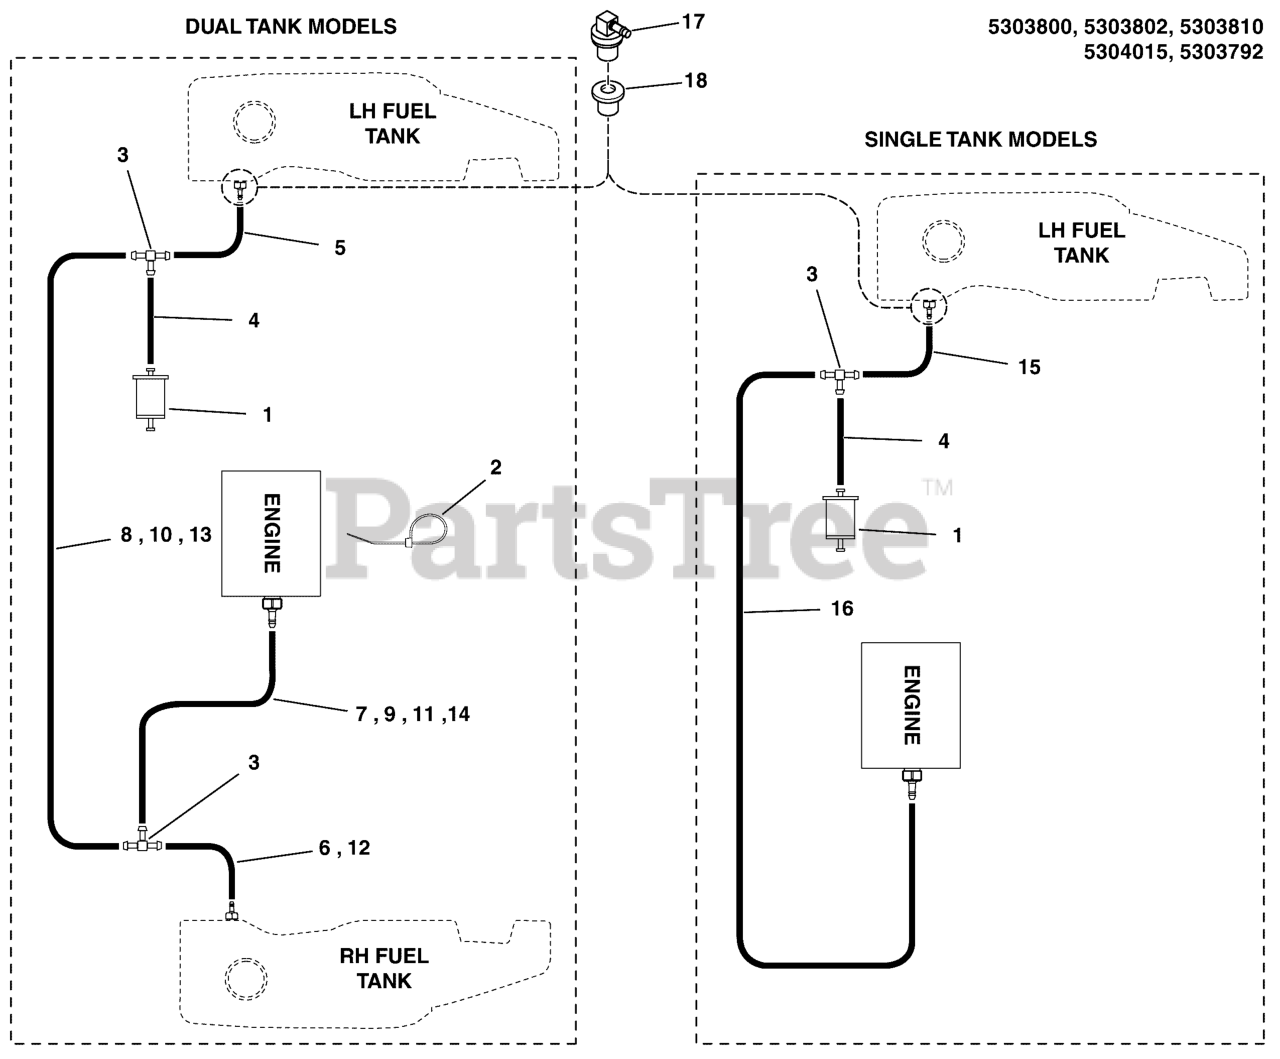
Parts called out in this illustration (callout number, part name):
1	FILTER, FUEL
2	TIE,SELF-LOCKING, 6"
3	FITTING, 3/16" TEE, BARB TYPE, HDPE
4	HOSE, VAPOR, 5MM ID, 2.00 LG
5	HOSE, VAPOR, 5MM ID, 21.50 LG
6	HOSE, VAPOR, 5MM ID, 39.00 LG
7	HOSE, VAPOR, 5MM ID, 5.00 LG
8	HOSE, VAPOR, 5MM ID, 24.00 LG
9	HOSE, VAPOR, 5MM ID, 22.00 LG
10	HOSE, VAPOR, 5MM ID, 16.00 LG
11	HOSE, VAPOR, 5MM ID, 12.00 LG
12	HOSE, VAPOR, 5MM ID, 35.00 LG
13	HOSE, VAPOR, 5MM ID, 15.00 LG
14	HOSE, VAPOR, 5MM ID, 9.00 LG
15	HOSE, VAPOR, 5MM ID, 39.00 LG
16	HOSE, VAPOR, 5MM ID, 18.00 LG
17	REMOTE VENT ASSEMBLY
18	GROMMET
